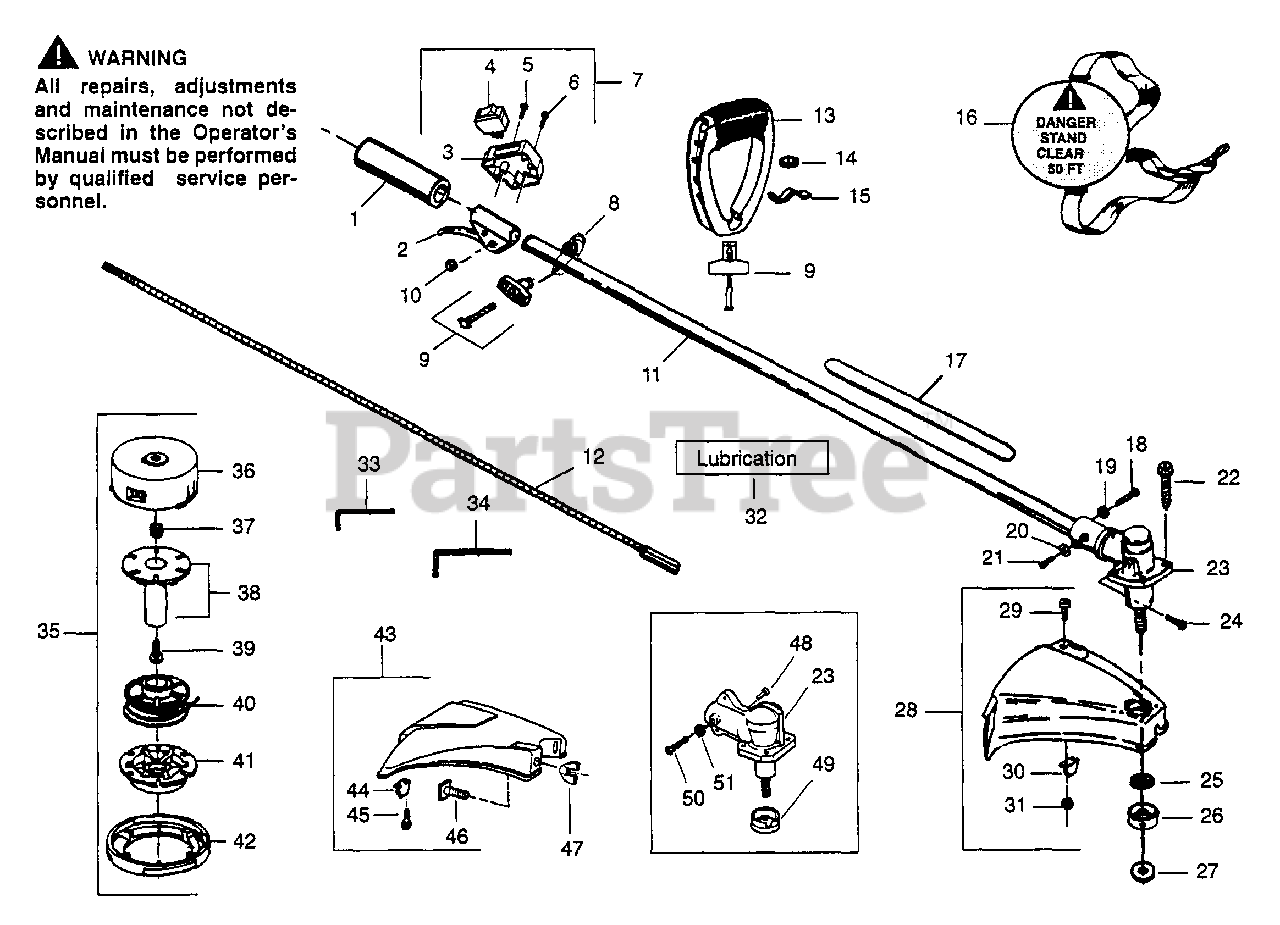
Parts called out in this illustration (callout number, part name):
2	Throttle Housing Ass'y.
3	Switch Cover
7	On/Off Switch Kit
8	Harness Clamp
9	"T" Handle
11	Drive Shaft Housing Type 1
11	Drive Shaft Housing Type 2
12	Drive Shaft
13	Assist Handle
16	Shoulder Strap
17	Shaft Warning Decal
19	Lockwasher
20	Lockwasher
23	Gear Box Ass'y. Type 1
23	Gear Box Ass'y. Type 2
27	Grass Washer
28	Shield Kit Ass'y. - Type 1
30	Line Limiter
31	Nut
32	Shaft Lubrication
33	Hex Wrench (5/32)
34	Hex Wrench (3/16)
35	Cutting Head Ass'y.
36	Hub Ass'y.
38	Locking Plate Kit
40	Spool w/Line
41	Release Button
43	Shield Kit Ass'y. - Type 2
44	Line Limiter - Type 2
45	Screw - Type 2
46	Bolt - Type 2
47	Wingnut - Type 2
48	Screw-Pinch Clamp - Type 2
49	Dust Cup - Type 2
50	Screw-Locator - Type 2
51	Lockwasher-Locator - Type 2
